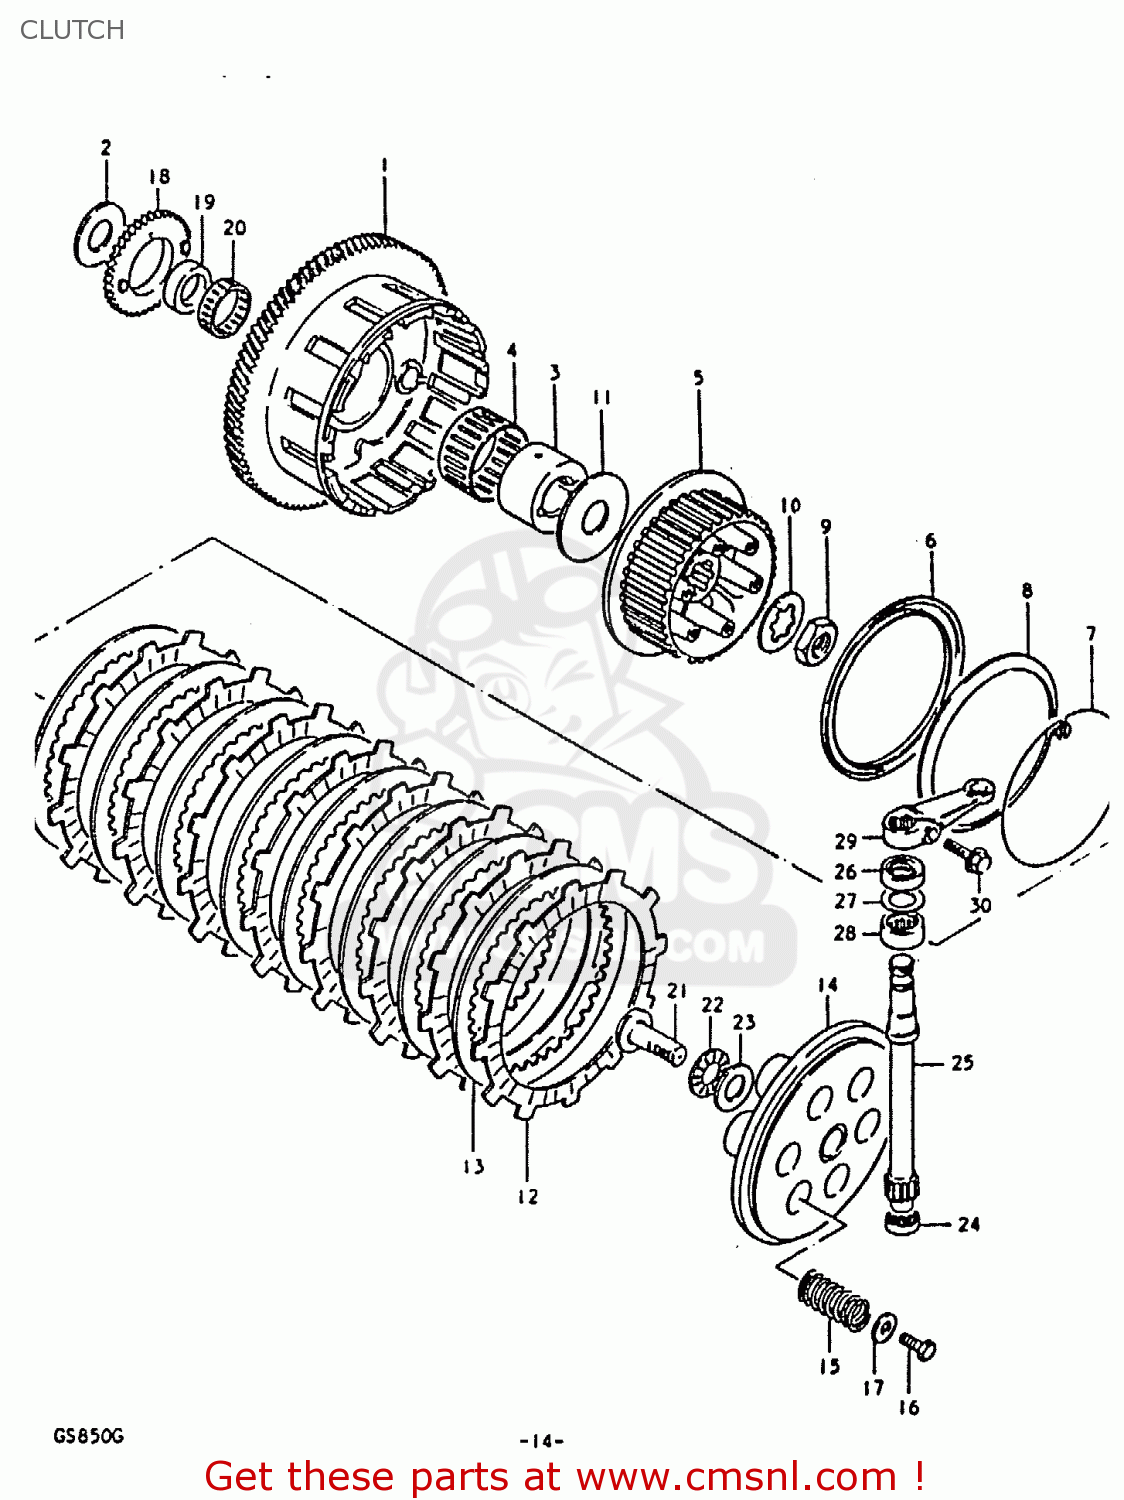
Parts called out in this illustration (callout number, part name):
1	GEAR ASSEMBLY,PRIMARY DRIVE
2	WASHER
3	SPACER,PRIMARY DRIVEN
4	BEARING
5	HUB,CLUTCH SLEEVE
6	SEAT,WAVE WASHER
7	RING,STOPPER
8	WASHER
9	NUT
10	WASHER,LOCK
11	WASHER(25X66X3.5)
12	PLATE,CLUTCH DRIVE (MCA)
13	PLATE,CLUTCH DRIVEN(T:2.0) (NAS)
14	DISC,CLUTCH PRESSURE
15	SPRING
16	BOLT, UPPER
17	WASHER
18	GEAR,OIL PUMP DRIVE
19	SPACER,OIL PUMP DRIVE GEAR
20	BEARING(36X40X10)
21	RACK,CLUTCH RELEASE
22	BEARING(15X28X2)
23	WASHER
24	SEAL,OIL(10X16X5)
25	PINION,CLUTCH RELEASE
26	OIL SEAL
27	WASHER (14.2X22X1)
28	BEARING(15X22X12)
29	ARM,CLUTCH RELEASE
30	BOLT
